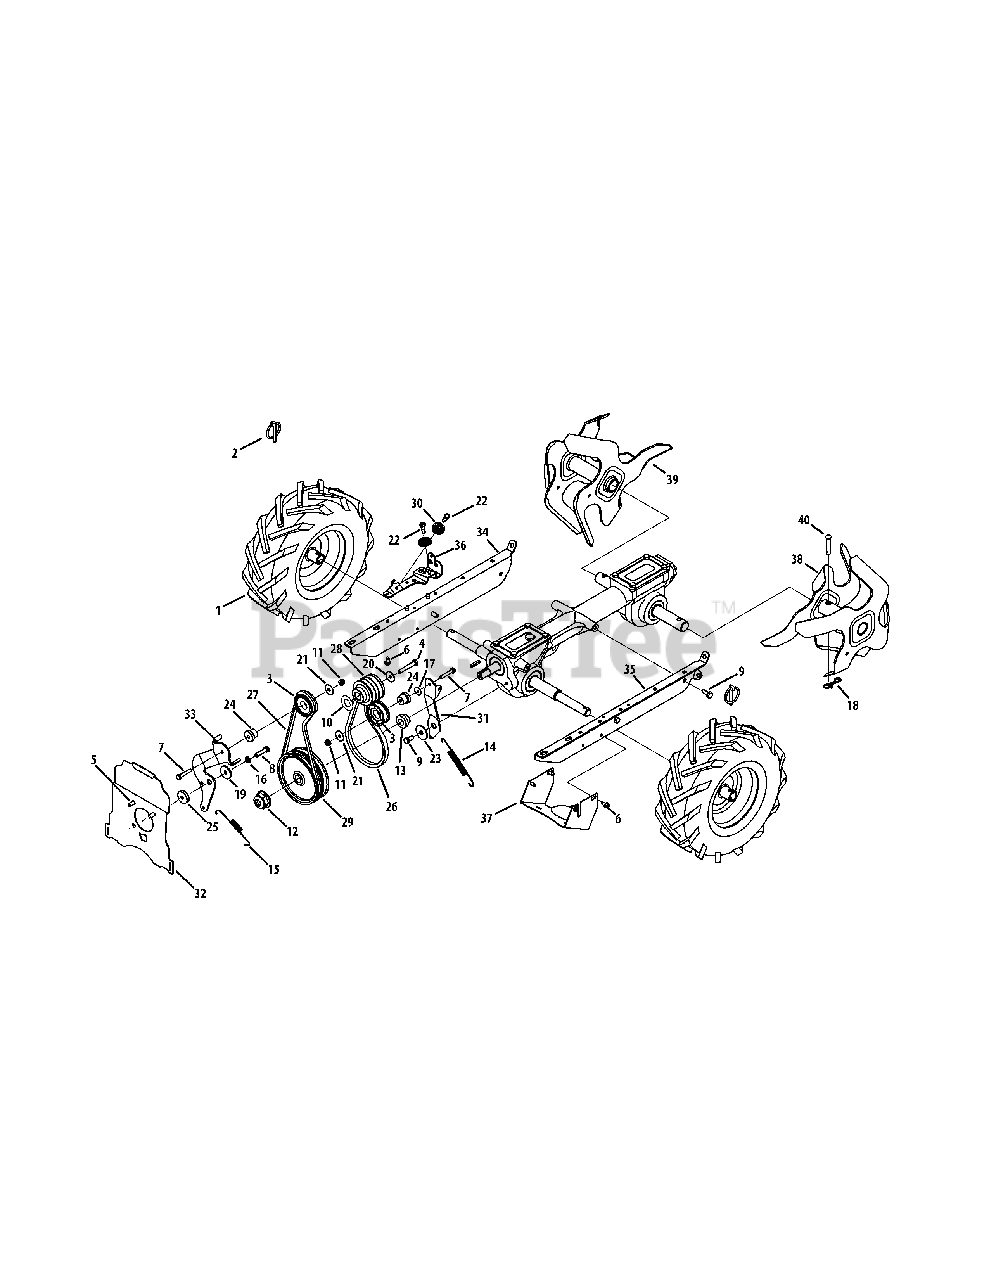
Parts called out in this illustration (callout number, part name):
1	Wheel Assy., 13 x 5 x 6 (B, C)
2	Klik Pin
3	Idler Pulley Assembly
4	Hex Head Screw, 3/8-24 x 2.25
5	Hex Head Screw, 5/16-24 x .625
6	Self Tapping Screw, 1/4-20 x .500
7	Hex Head Screw, 1/4-20 x 1.50
8	Hex Head Screw, 5/16-18 x 1.25
9	Hex Head Screw, 5/16-18 x .75, Patch
10	Washer, Flat, .760 x 1.50 x .120
11	Nylon Hex Lock Nut, 1/4-20
12	Nut, 9/16-18, Flange Lock
13	Hub, 5/8 Spline
14	Extension Spring, .480 OD X 5.00 LG
15	Extension Spring, LT5 PTO
16	Lock Washer, 5/16
17	Washer, .28 x .74 x .063
18	Cotter Pin, Bow Tie
19	Flat Washer, .330 X 1.25 X .120
20	Bell Washer, .396 x 1.140 x .095
21	Flat Washer, .265 x 1.0 x .030
22	Shoulder Screw, .342 x .335 1/4-28
23	Pivot Idler Spacer
24	Shoulder Spacer, .260 x .785 x .538
25	Pivot Idler Spacer
26	V-Belt, 4L x 25.375 Long
27	V-Belt, 3L x 29.125 Long
28	Engine Pulley
29	Transmission Pulley
30	Cable Roller
31	Idler Bracket, Forward
33	Idler Bracket, Reverse
34	Mounting Frame, RH
35	Mounting Frame, LH
36	Pulley Bracket
37	Pulley Shield
38	Tine Assembly, LH
39	Tine Assembly, RH
40	Clevis Pin, .375 x 1.75
